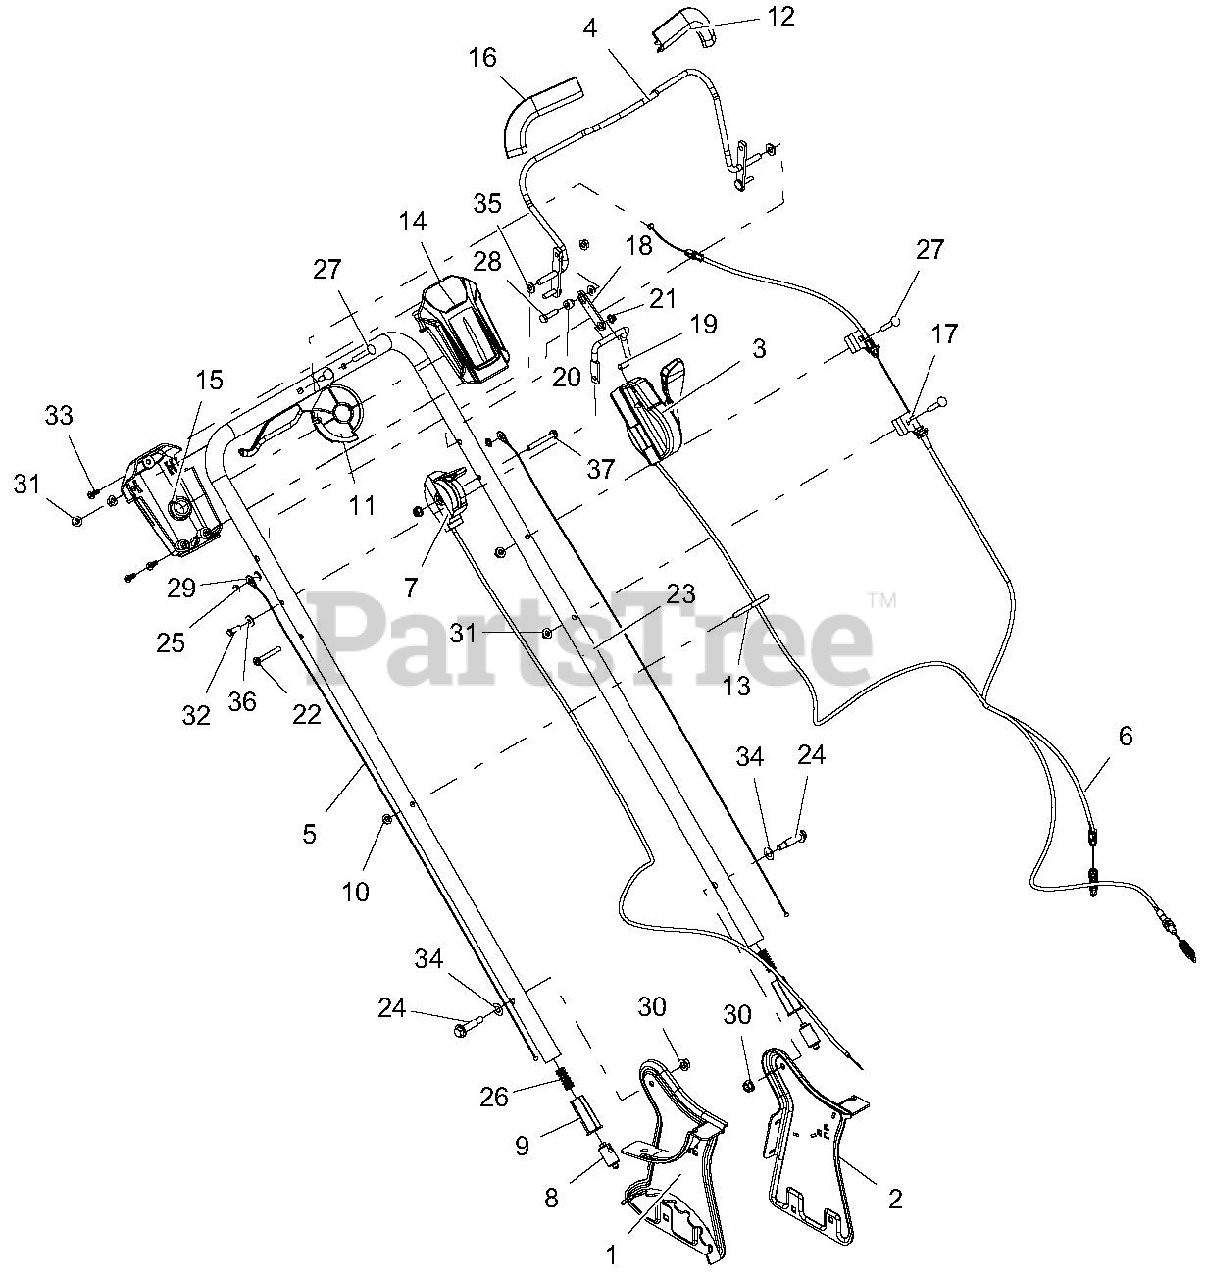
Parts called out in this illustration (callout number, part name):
1	SUPPORT, RH HANDLEBAR
2	SUPPORT, LH HANDLEBAR
3	ASSY, BBC CONTROL
4	WLDMT, OPC BAIL, BBC
5	CABLE, LM HANDLE ADJUST
6	CABLE, DRIVE CONTROL
7	CONTROL, THROTTLE
8	PLUNGER, HANDLEBAR LOCKING
9	INSERT, HANDLEBAR ADJUST
10	@NUT-LK-NYL-FLG .25-20 YWZC
11	HANDLE, DRIVE CONTROL
12	GUARD, FINGER - LH
13	HOLDER, RECOIL CORD
14	HOUSING, UPPER DRIVE CONTROL
15	HOUSING, LOWER DRIVE CONTROL
16	GUARD, FINGER - RH
17	BRKT, CABLE - DRIVE
18	COUPLER, BBC CONTROL
19	WIREFORM, BBC CONTROL
20	BSHG, BBC LATCH
21	BUSHING, NYLON, .31, SPLIT
22	SCR M6-1.0X45 DIN7985A PH YWZC
23	HANDLEBAR, LM
24	BLT-SHLDR, .50X1.15X.312-18GR5
25	NUT-PUSH .25X.50 O.D.
26	SPRING, COMPRESSION
27	@BLT-RDHDSQNK .25-20X1.50 G5YZ
28	@BLT-HEX .25-20X1.00 GR5 YWZC
29	RG-RTNG-EXT .250X.010
30	@NUT-LK-TOP-FLG .31-18 YWZC
31	@NUT-LK-TOP-FLG .25-20 YWZC
32	PIN, .25 X .75
33	SCR-TAP 12-14X.75PLSTITE @BLZC
34	WSHR,.385X.745X.030 STL YWZC
35	@WSHR-FL-STL.344X.688X.065YWZC
36	@WSHR-FL-STL.281X.62X.065 YWZC
37	SCR, .25-20X2.00 PH PAN YWZC
